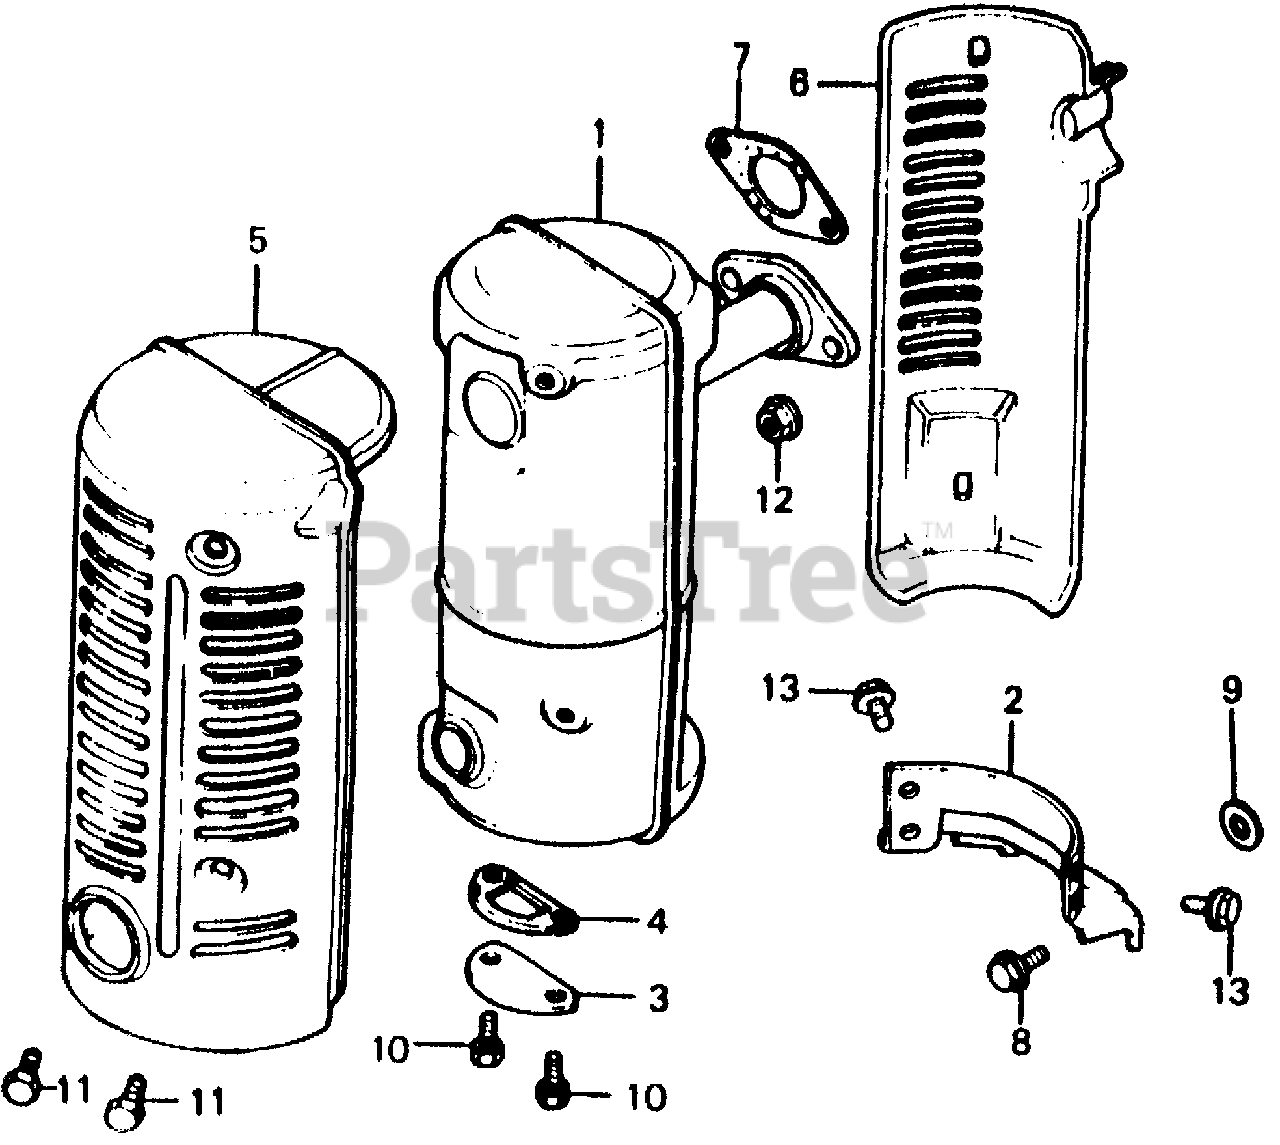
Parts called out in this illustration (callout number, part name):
1	MUFFLER ASSY.
2	STAY, MUFFLER
3	LID, MUFFLER
4	GASKET, MUFFLER LID
5	PROTECTOR A, MUFFLER
6	PROTECTOR B, MUFFLER
7	GASKET, MUFFLER
8	BOLT, FLANGE (8X16)
9	WASHER (8MM)
10	BOLT, HEX. (6X12)
11	BOLT, HEX. (6X6)
12	NUT, FLANGE (8MM)
13	BOLT, FLANGE (6X10)
